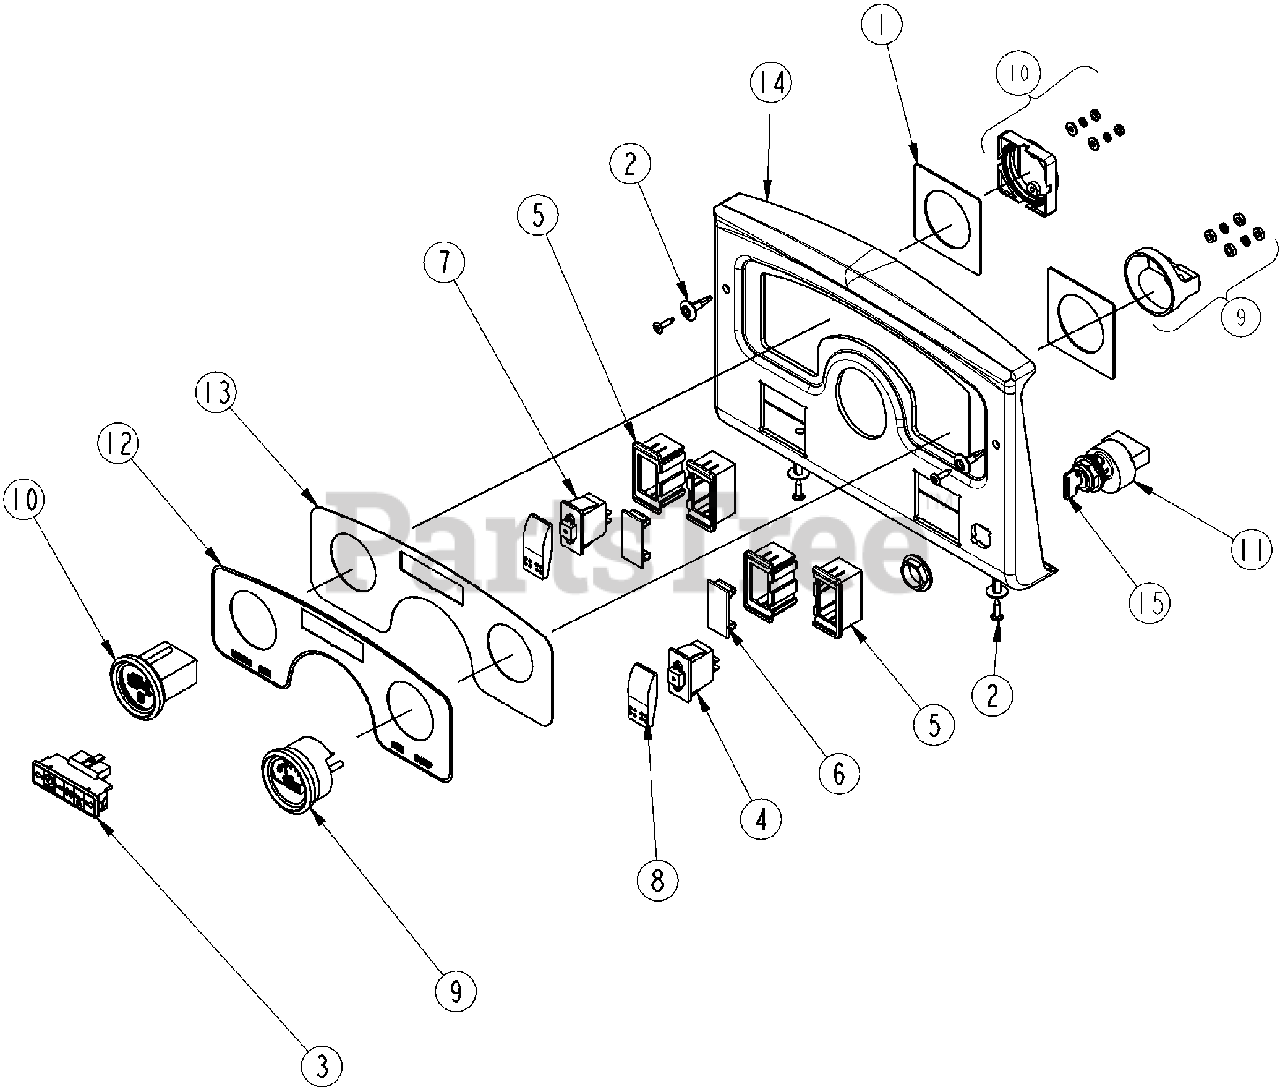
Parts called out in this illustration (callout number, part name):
1	DASH BACKER PLATE
2	RIVET, 1/4
3	INDICATOR LIGHT STRIP 8-PIN Replacement Bulb 833-418c
4	DUMP SWITCH WAYTEK 44304
5	SWITCH MOUNT END
6	PANEL PLUG
7	SWITCH ROCKER SPST
8	SWITCH ACTUATOR
9	GAUGE, VOLT METER
10	GAUGE, HOUR METER
11	IGNITION SWITCH W/2 KEYS (6-PIN)
12	DECAL INSTRUMENT PANEL
13	INSTRUMENT PANEL
14	DASH TRUCK
15	KEY W/SHIELD (RP FOR 833-336C)
